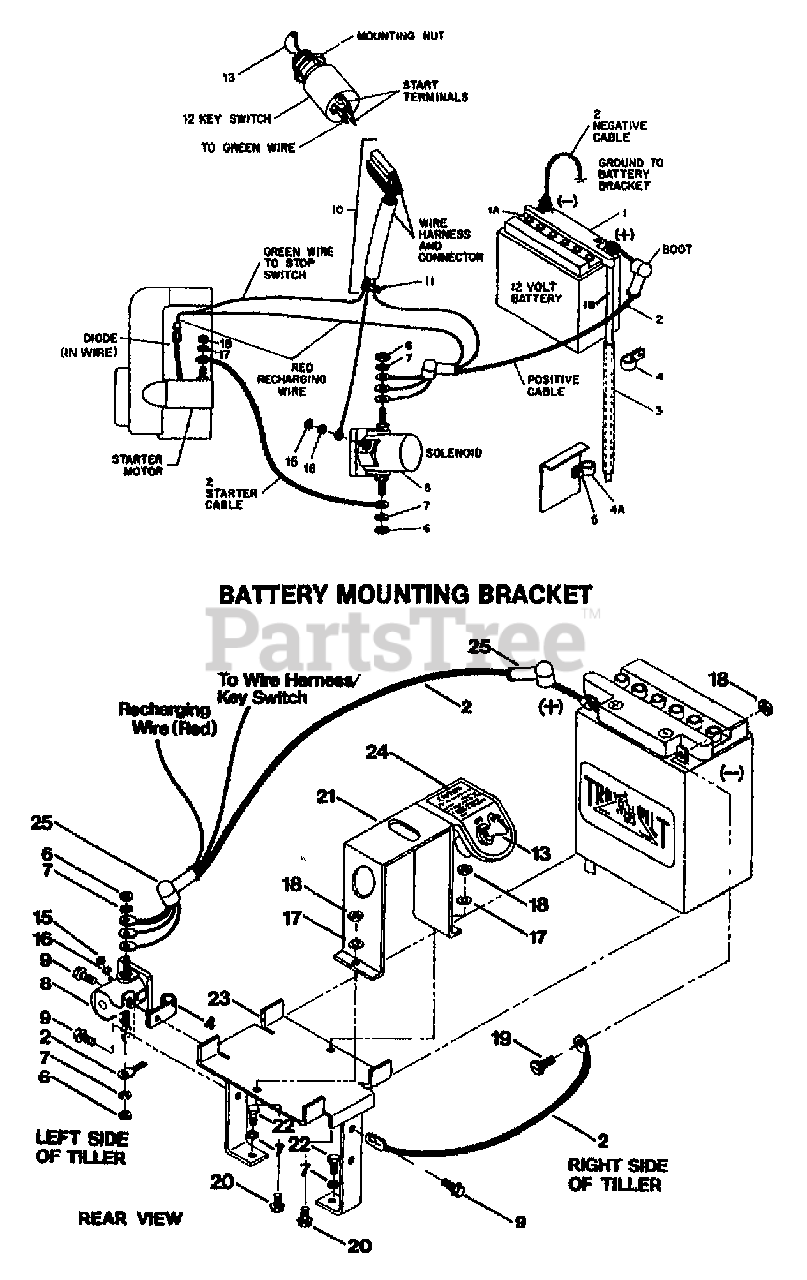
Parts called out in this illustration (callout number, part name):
1	BATTERY - 12 VOLT, 12 AMPHERE
1A	CAP-YELLOW
1A	CAP-BATTERY WHITE (PONY)
1B	TUBE-VENT BATTERY/HSE
2	CABLE-BATTERY
3	TUBING-RUBBER
4	CLAMP (SMALL)
4A	CLAMP (LARGE)
5	SCR-HHC 5/16-18X.75 GR 5 ZP
6	NUT-HEX 5/16-24
7	WASHER-LK .312 ZP
8	KIT-SOL W/HDW
9	SCR-HWH 1/4-20 X .5 STH
10	HARNESS-WIRE 6HP (AVAIL. AS COMPLETE UNIT ONLY)
11	TIE-TWIST LOCK
12	KEYSWITCH W/KEYS
13	KEYS(1 PAIR) FOR SWITCH
15	NUT-HH M10-32X.125
16	WASHER-EXTERNAL TOOTH 1
17	WASHER-LK .25 ZP
18	NUT-HEX 1/4-20 ZP
19	BOLT-SLHH 1/4-20 X .5 (REPLACEMENT HARDWARE FOR CABLE TO BATTERY CONNECTION)
20	SCR-CARR 1/4-20X1.25
21	PLTE-KEYSWITCH W/DEC-PONY 3 (INCL. #20418, DECAL)
22	SCR-HH 5/16-18X1.0 G5 ZP
23	BRKT-BATTERY PNT
24	DECAL-KEYSWITCH TILLER
